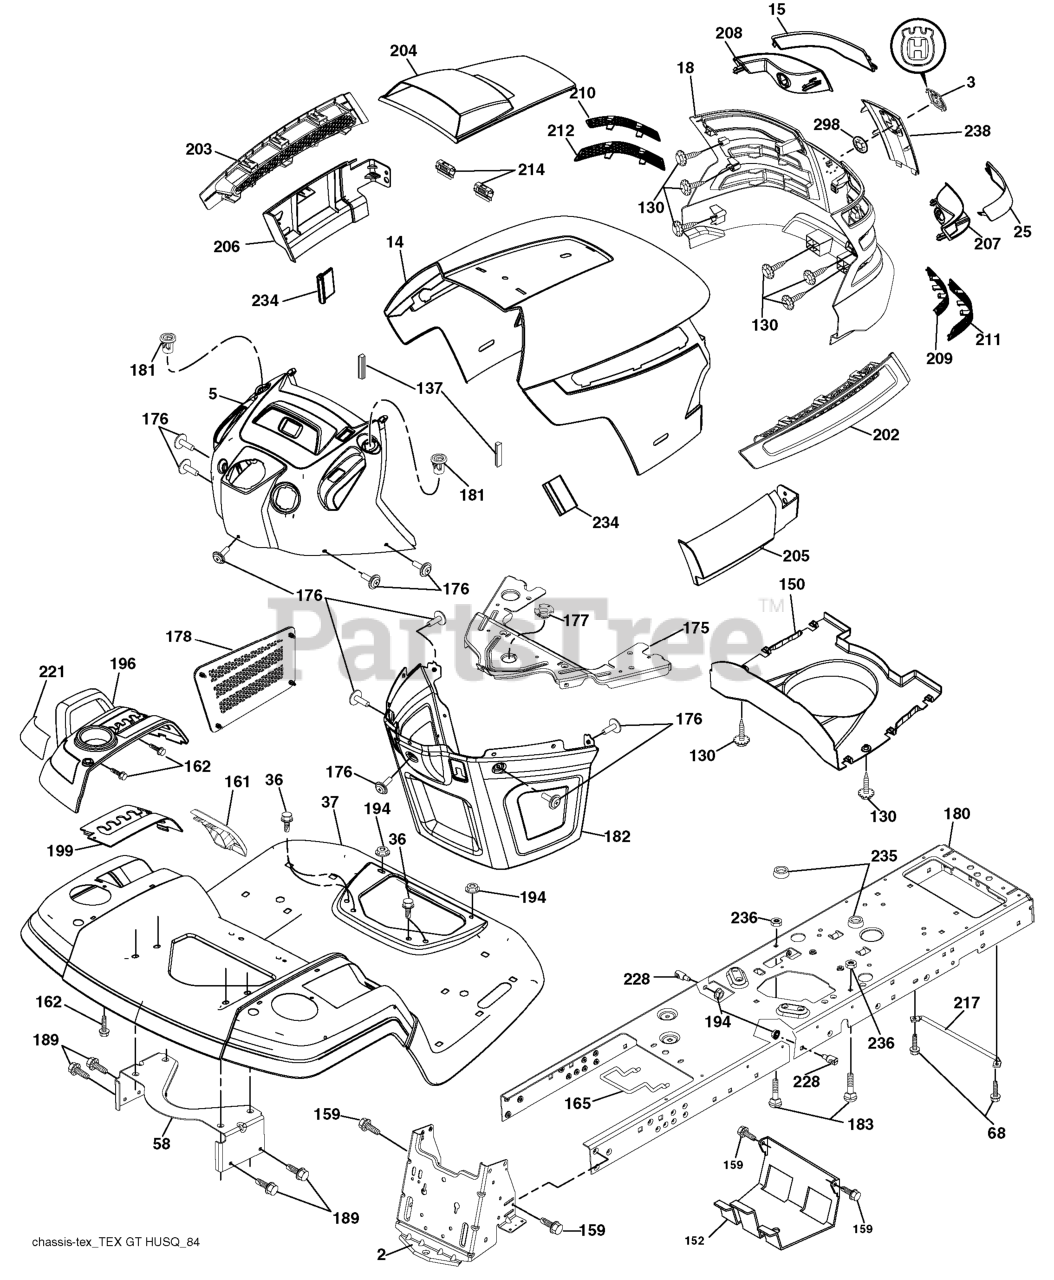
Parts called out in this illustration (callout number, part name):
2	DRAWBAR.STGT
3	RP LOGO
5	DASH.ASM.GTHUSQTX.RGS.ELECT.CK
14	HOOD
15	LENS.LH.TEX.GT.HUSQ.CL
18	GRILL.ASM.HUSQ.TG/CRD.W/TRIM
25	LENS.RH.TEX.GT.HUSQ.CL
36	SCREW 5/16"
37	FENDER.PNT.TX.GT.CH/FW.ORANGE
58	BRKT.SUPPORT.FNDR/TANK
68	Screw 5/16-18 x 1/2
130	SCREW.#10 X 0.750.BOS
137	BUMPER DASH
150	AIR.DUCT.HOOD.TEX.GT.HUSQ
152	SHIELD.BROWNING/DEBRIS
159	SCREW, 3/8-16X3/4
161	CONSOLE.FUEL.WINDOW.HU
162	SCREW.HI-LO.CONSOLE
165	SUPPORT.TANK.REAR.B/TE
175	PLATE.CROSSMEMBER.HUSQ
176	SCREW.#10-24X5/8.RN.QU
177	BUSHING, STEERING
178	CARGO.ASM.NET.TXGT.W/C
180	CHASSIS.STAMPING.LT/GT
181	BUSHING.MNT.FEND.CRGO.
182	DASH.LOWER.COMMON.12V.ADAPTOR
183	BOLT.5/16-18X1-1/4 FULL THD
189	SCREW
194	NUT LOCK HEX FLANGE 5/16-18
196	CONSOLE.ASM.DCKLFT.W/RF.HQ.DLR
199	PLATE.DECK.LIFT.HUSQVARNA.GT
202	VENT.SIDE.HOOD.HUSQ.RH.GREY
203	VENT.SIDE.HOOD.HUSQ.LH.GRAY
204	HOOD VENT
205	SKIRT.HOOD.SIDE.HUSQ.RH.GREY
206	SKIRT.HOOD.SIDE.HUSQ.LH.GREY
207	BEZEL.RH.TEX.GT.HUSQ
208	BEZEL.LH.TEX.GT.HUSQ
209	INSERT.HEX.GRILL.HUSQ.GREY
210	INSERT.HEX.GRILL.HUSQ.
211	INSERT.HEX.GRILL.HUSQ.
212	INSERT.HEX.GRILL.HUSQ.
214	CLIP.RETAINER.TINNER.
217	ROD.PIVOT.HOOD
221	REFLECTOR.LH.TEX GT HU
228	STUD.FASTNER.W/ANTI-ROTATE
234	BUMPER.HOOD.TEX.HUSQVARNA
235	SPACER FENDER
236	NUT.CENTERLOCK.5/16-
238	TRIM.HUSQ.TG/CRD.SERVICE
298	NUT PUSH M
